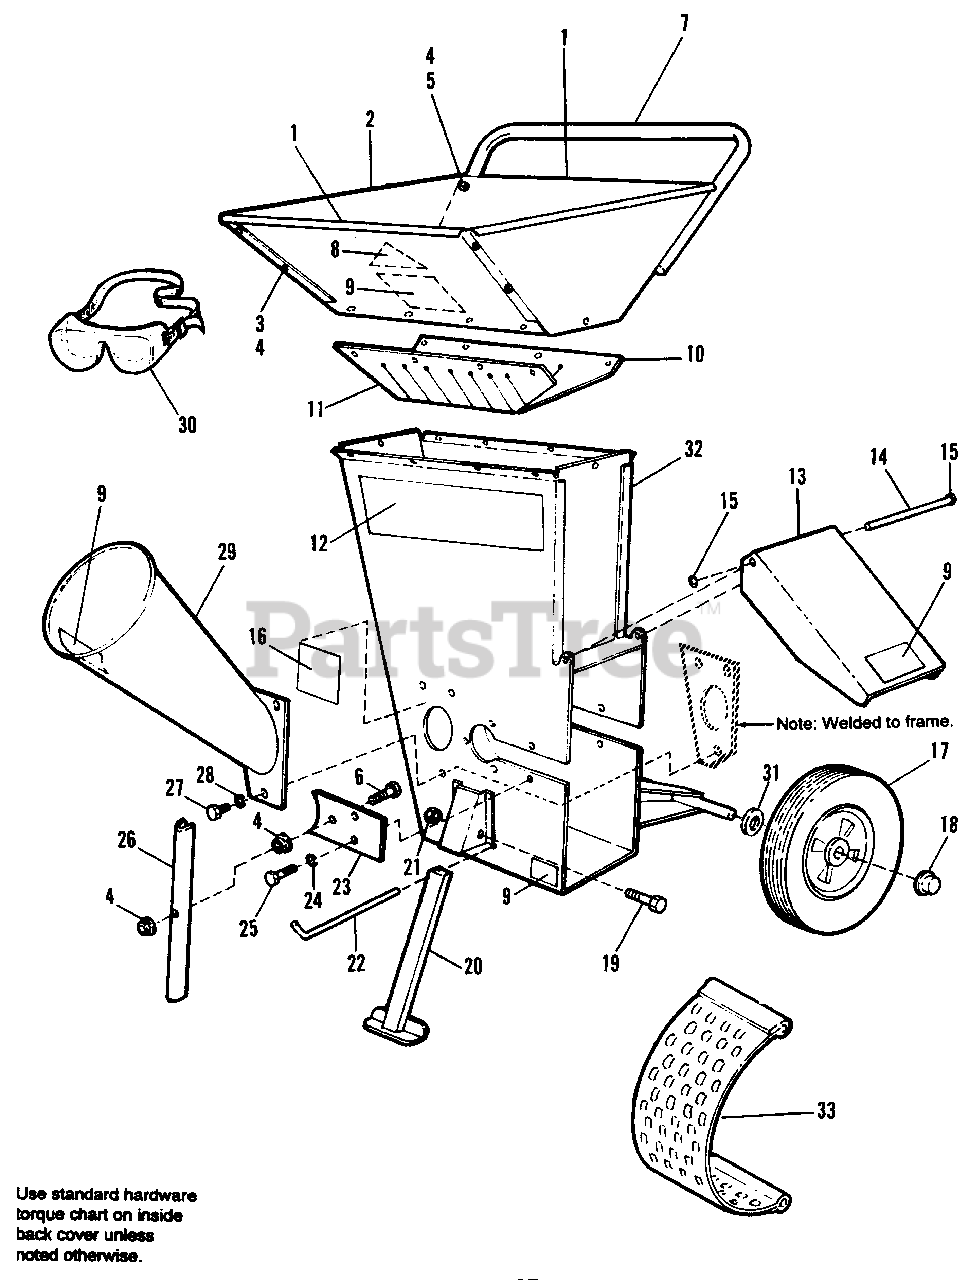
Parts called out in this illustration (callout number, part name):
2	HOPPER SIDE
3	SCREW, Truss Hd., Phillips, 1/4-20 x 5/8
4	NUT, Hex, Flange, Whiz Lock, 1/4-20
5	CAPSCREW, 1/4-20 x 1 1/2
6	SCREW, Truss Hd., Phillips, 1/4-20 x 1-1/2
8	DECAL, OPEI
9	DECAL, Danger
10	GUARD, Lexan, Engine Side
11	GUARD, Lexan, Cone side
12	DECAL, Simplicity, 612
12	DECAL, Baker, 5 HP
12	DECAL, Baker, 5 HP, Honda
12	DECAL, Red Cycler
13	DEFLECTOR, Discharge
14	DEFLECTOR, Rod
15	PUSH NUT, 1/4
16	LABEL (Shipping Only)
17	WHEEL & TIRE ASSY.
18	PUSH NUT, 5/8
19	CAPSCREW, Hex, 5/16-18 x 1-3/4
21	NUT, Nylock, 5/16-18
22	ROD, Screen
23	PLATE, Closure
24	LOCKWASHER, 5/16
25	CAPSCREW, Hex, 5/16-18 x 1/2
27	CAPSCREW, Hex, 5/16-18 x 3/4
28	LOCKWASHER, Split, 5/16
29	CONE, Chipper Hopper
31	WASHER, Plain, 21/32 x 1-1/4 x 1/16
33	SCREEN, 3/8" Dia. circle openings
33	SCREEN, 1-1/2" Dia. circle openings
33	SCREEN, Oblong slot openings
33	SCREEN, 3/4" Dia. circle opening
